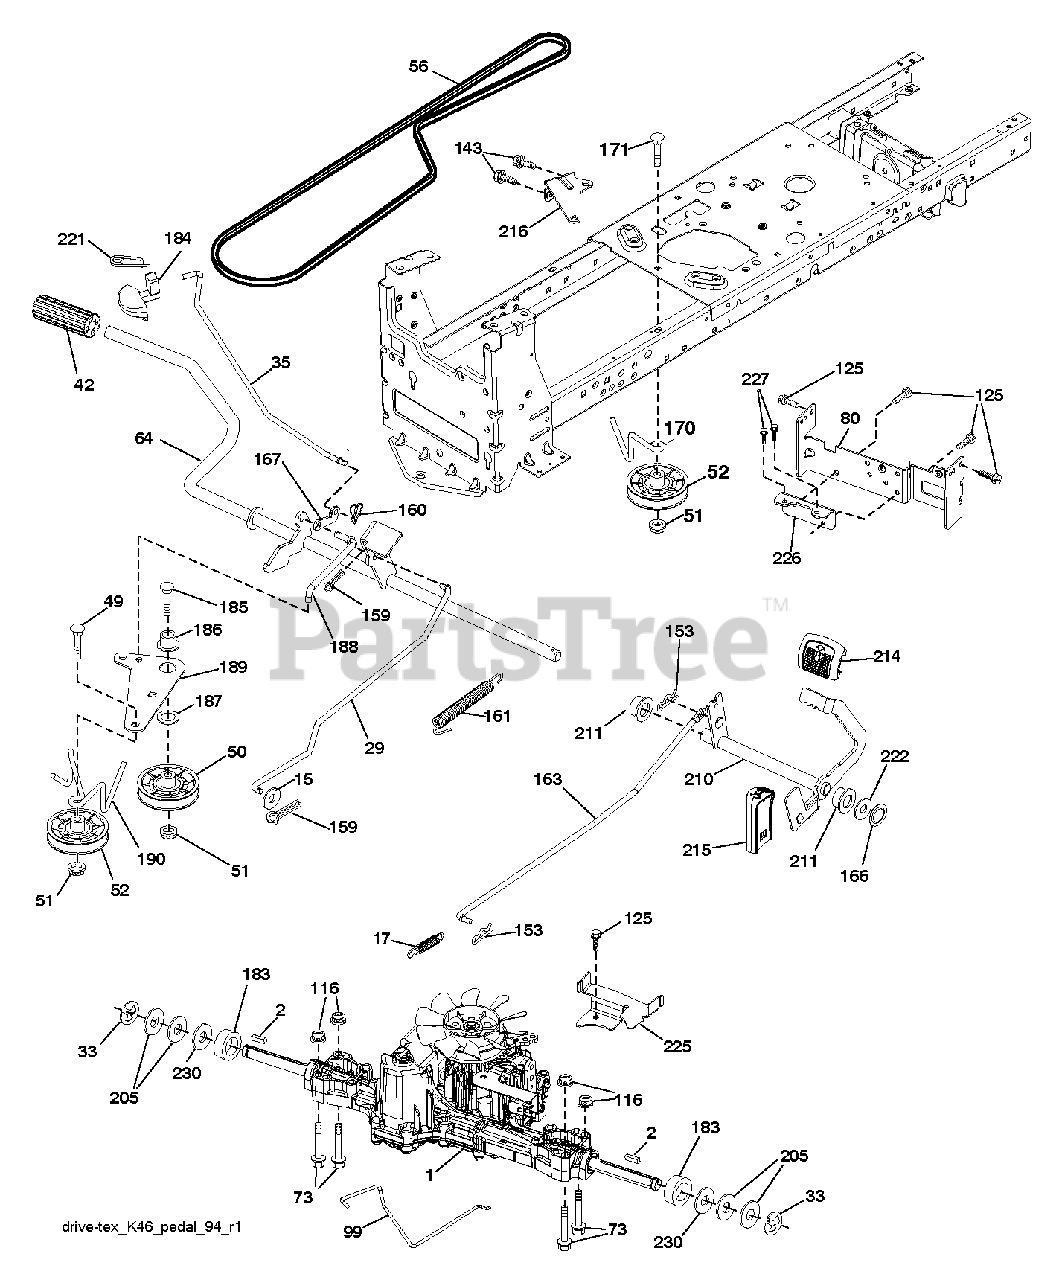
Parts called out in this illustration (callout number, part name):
2	SQUARE KEY
15	WASHER
17	SPRING, BREAK
29	ROD.BRAKE.K46
33	E-RING LT
42	PEDAL COVER T
50	IDLER.FLAT.910.OFFSET
52	IDLER.V-GROOVE.910.OFFSET
64	SHAFT.ASM.PEDAL.BRK.CN
99	ROD.SPRING.BYPASS.K46.LT.Z
116	NUT LOCK HEX FLANGE 5/16-18
125	SCREW
143	SCREW LT
159	COTTER PIN
160	RETAINER CLIP
161	SPRING, RETURN LT
166	NUT.PUSH.625
167	LATCH BRAKE PARKING
170	KEEPER.V-IDLER.CENTER.
183	SPACER AXLE
186	SPACER.RETAINER
188	LINK.CLUTCH.GROUND DRI
189	BELLCRANK.GRDDRIVE.NST
190	KEEPER.BELLCRANK.DRIVE
210	ROCKER.ASM.PEDAL.CONTR
211	BEARING RER
214	PAD PEDAL FORWARD
215	PEDAL.REVERSE.TEX.GT.4
216	BRKT.PULLEY.IDLER.WTEX
221	RETAINER.SPRING.CLIP.H
222	WASHER 21/32 X 1-1/4 X 10 GA.
225	KEEPER.BELT.TRANSAXLE.
226	BRACKET MOUNT TORQUE
